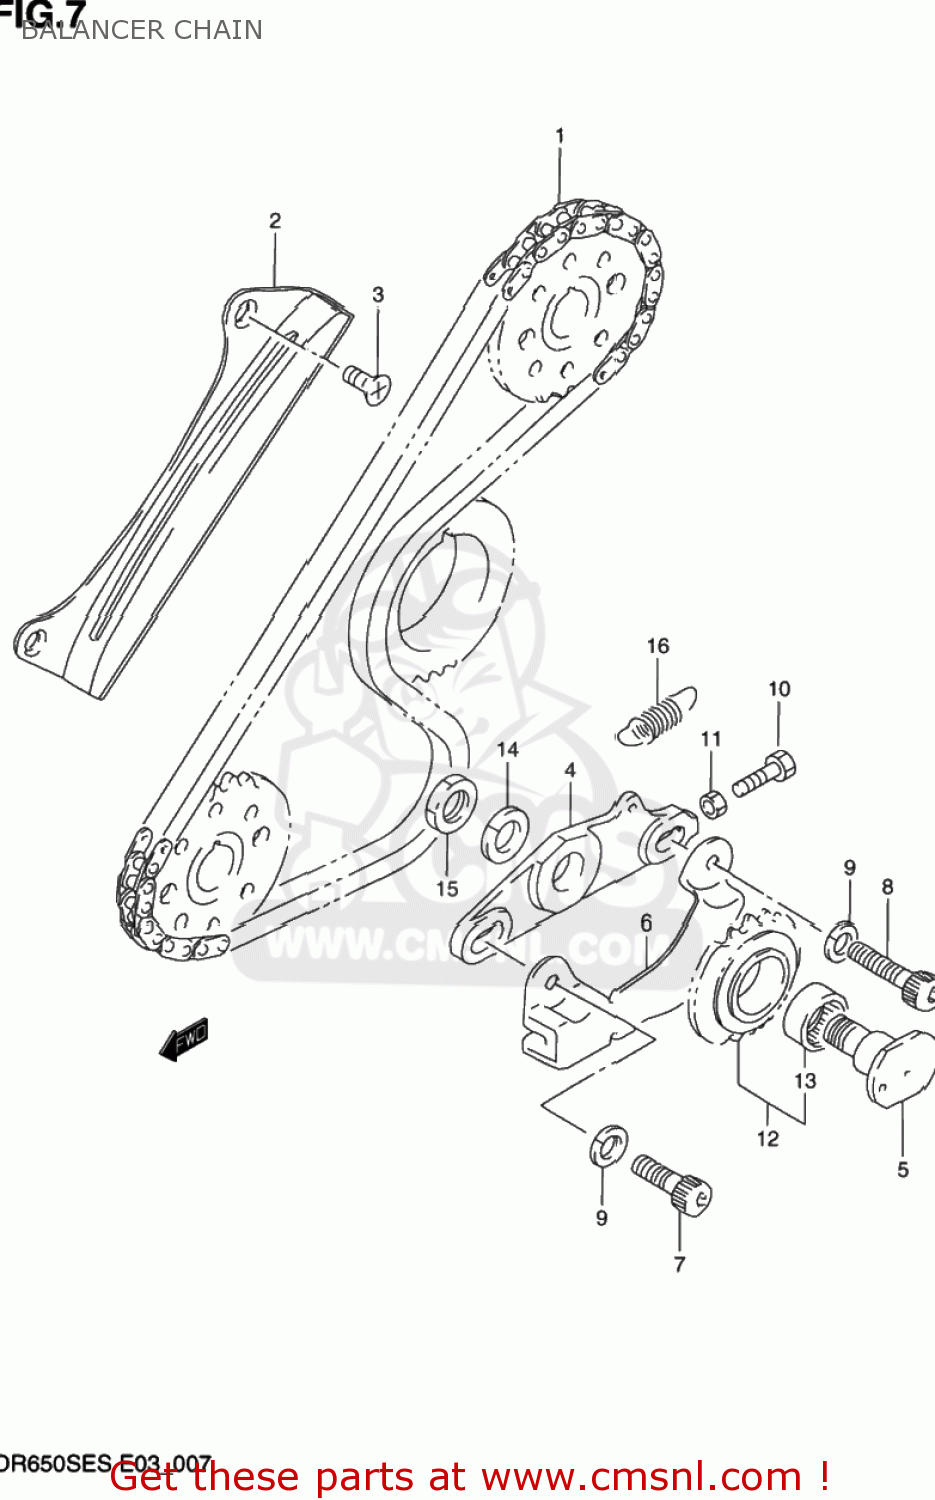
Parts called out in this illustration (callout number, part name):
1	CHAIN,BALANCER
2	GUIDE,BALANCER CHAIN
3	SCREW ,6X16
4	BRACKET,BALANCER CHAIN
5	SHAFT,BALANCER CHAIN TENSIONER
6	GUIDE,BALANCER CHAIN TNSN
7	BOLT(8X22)
8	BOLT
9	LOCK WASHER
10	BOLT
11	NUT
12	SPRKT,BALANCER CHAIN TENSIONER
13	BEARING(17X23X12)
14	WASHER,LOCK
15	NUT
16	SPRING
